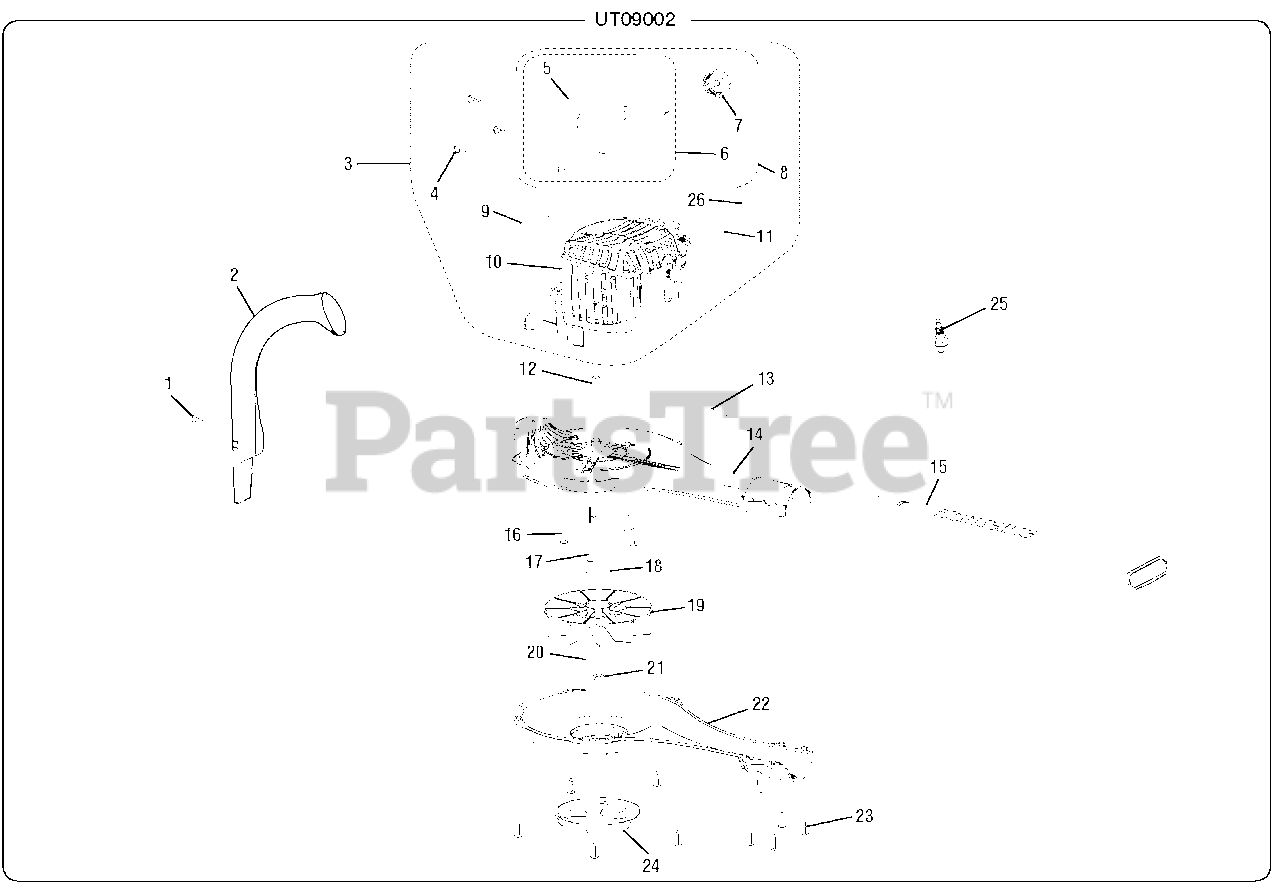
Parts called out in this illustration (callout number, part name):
1	Screw (10-14 x 1/2 in.)
3	Power Head and Fuel Tank Assembly
4	Screw (M4 x 10 mm)
5	Fuel Tank
6	Fuel Tank Assembly
8	Fuel Tank and Cap Assembly.
9	Logo Label
10	26cc Power Head Assembly
11	Choke Label
12	Crankshaft Spacer
13	Starting Label
14	Top Volute
15	Upper Nozzle
16	Screw (10-14 x 7/8 in.)
17	Screw (M4)
19	Fan
21	Nut (3/8-24)
22	Bottom Volute
23	Screw (10-14 x 3/4 in.)
24	Volute Plate
25	Spark Plug (Champion RCJ6Y)
26	Safety Icon Strip
